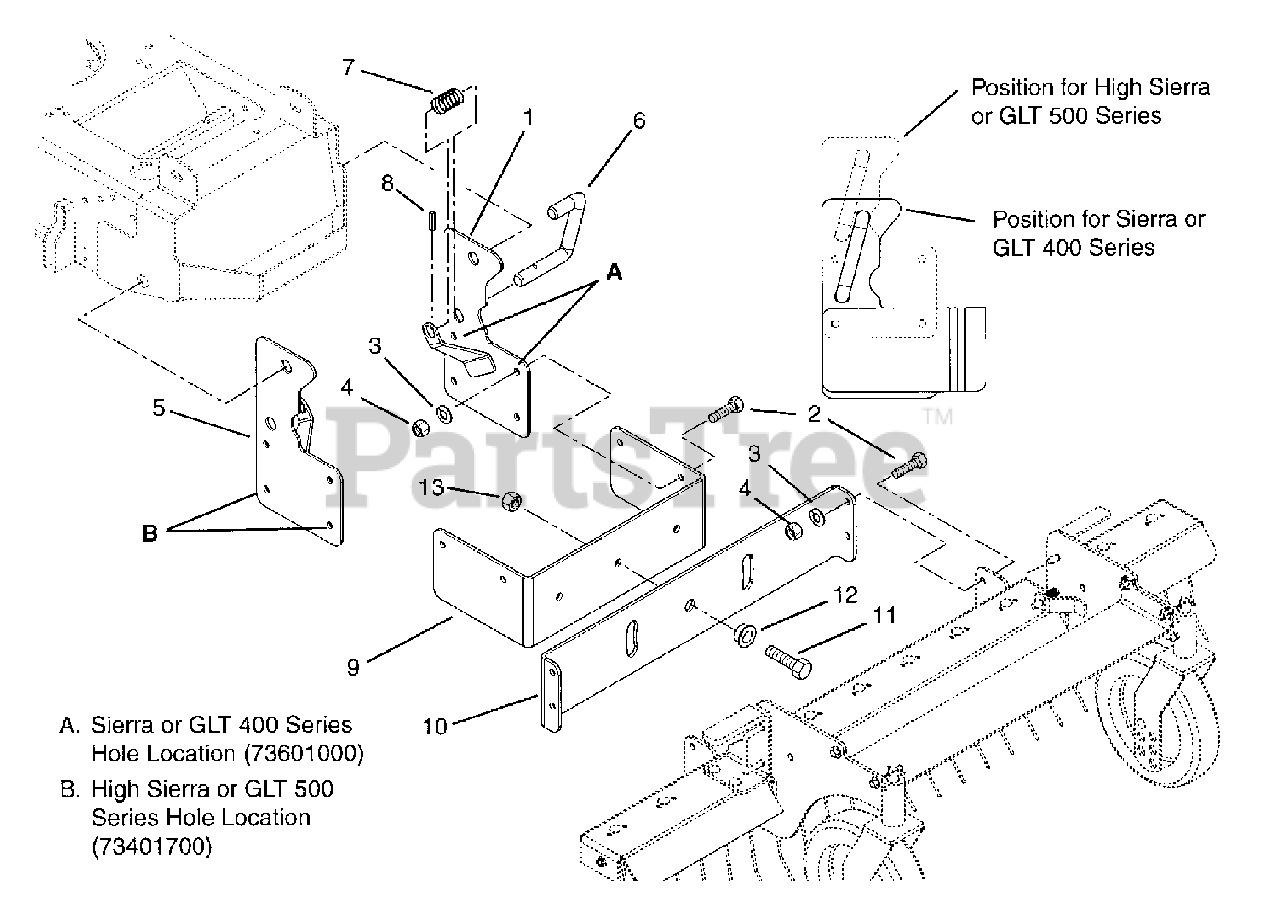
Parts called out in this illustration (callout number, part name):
1	PIVOT FRAME LH
2	@BLT-HEX .31-18X.75 GR5 YWZC
3	@WSHR-LK .31X.078 REG YWZC
4	@NUT-HEX .31-18 YWZC
5	PIVOT FRAME RH
6	PIN, LATCH
7	SG-COMP .072X.77X1.75
8	PIN-ROLL .188X1.00
9	STABILIZER - PIVOT FRAME
10	STABLIZER - CHANNEL SUPPORT
11	@BLT-HEX .38-16X1.00 GR5 YWZC
12	BSHG-FLG .390X.625X.328X.875
13	@NUT-LK-CTR .38-16 YWZC
